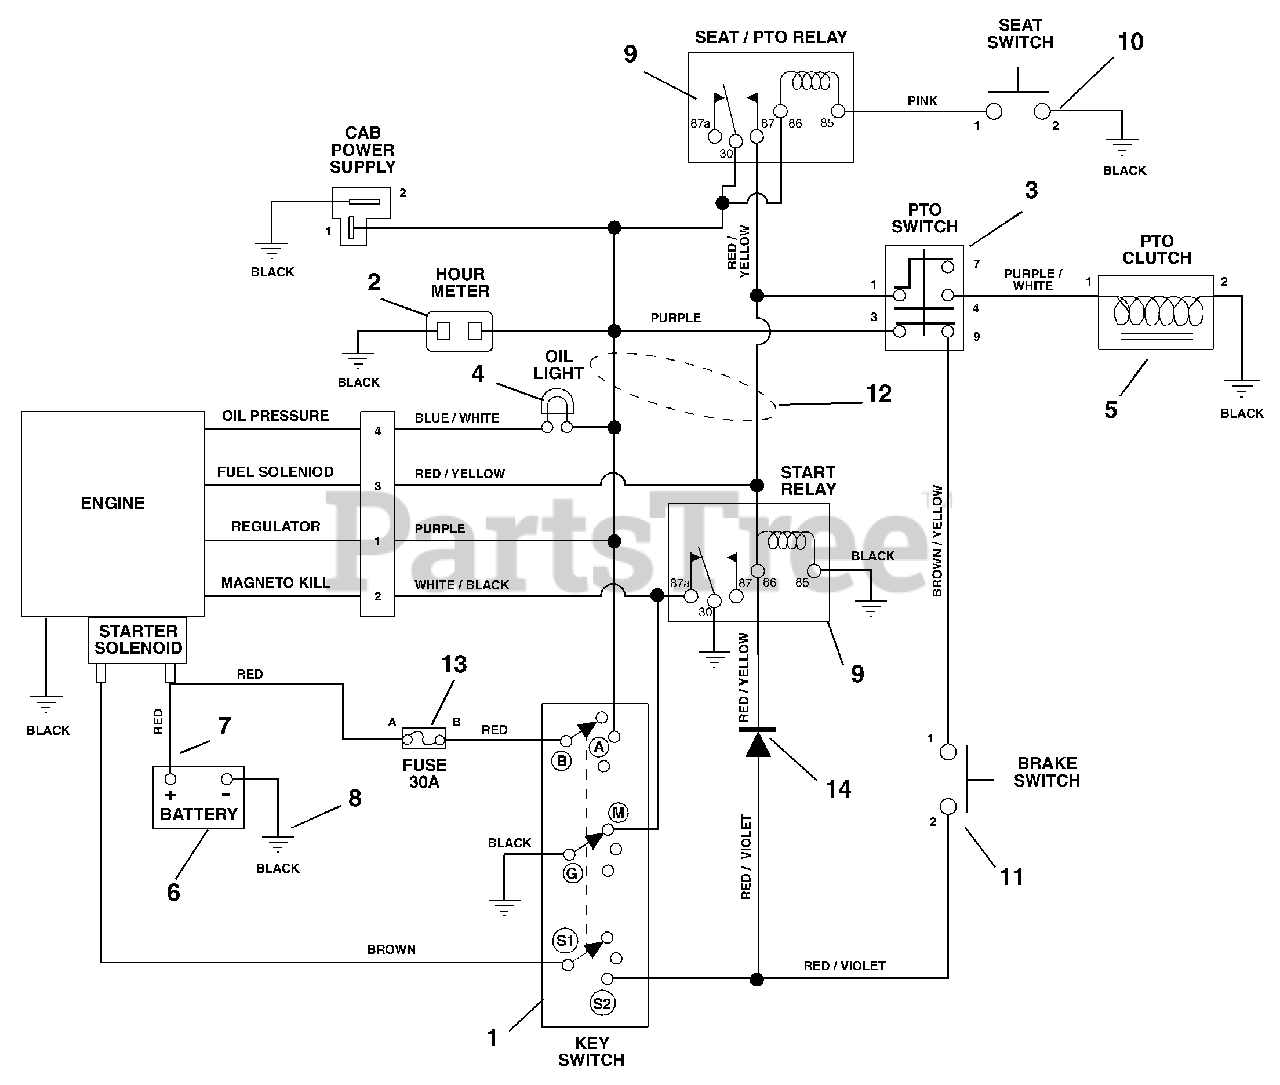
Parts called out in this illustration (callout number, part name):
1	Key Switch
2	Hour Meter
3	Switch-Clutch With Retainer Ring
4	Light-Indicator
5	Electric Clutch
6	Battery with Tube
7	Cable-Battery To Solenoid
8	Ground Cable
9	Relay
10	Seat Switch
11	Switch-Single Pole
12	Harness Kohler
13	Fuse, 30 Amp
14	Molded Diode Plug-Black 1-Amp
